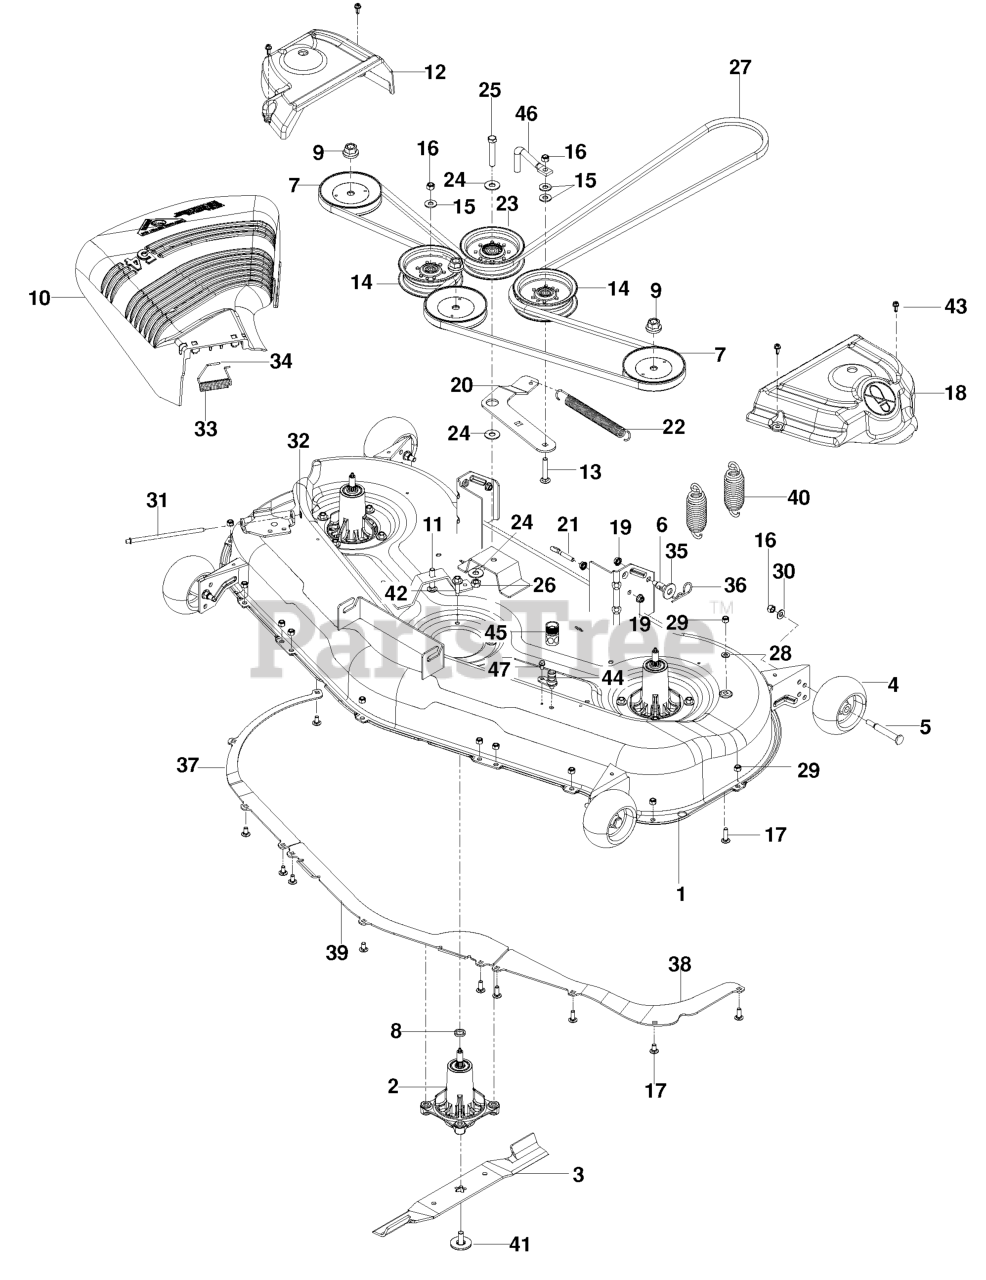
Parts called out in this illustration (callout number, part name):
1	DECK W/DECALS - RZ54
2	MANDREL GREASABLE
3	BLADE.BAGGING.54"
4	GAUGE WHEEL
5	SHOULDER BOLT 1/2X2-5/8 ZD SPE
6	STUD.FASTNER.W/ANTI-ROTATE
7	PULLEY
8	WASHER-SPACER
9	LOCKNUT - 9/16
10	DEFLECTOR, 54"
11	RHSNB 3/8C X 2
12	BELT SHIELD, RT
13	CARRIAGE BOLT 3/8-16 X
14	PULLEY.IDLER.2006
15	WASHER 3/8 FLAT
16	NUT 3/8-16 NYLOC
17	BOLT 5/16C X 3/4" CARRIAGE
18	BELT SHIELD, LT
19	5/16-18 NYLOC FLANGE NUT
20	ARM.IDLER.BLACK
21	EYE BOLT 5/16 X 3.50
22	SPRING, DECK BELT
23	PULLEY.IDLER.MWR.STATI.LH
24	WASHER 7/16 FLAT ZD
25	BOLT 7/16-14 X 2-1/2 GR 5 ZD
26	7/16-14 HEX NUT W/NYL RING ZD
27	BELT.DECK.52".54"
28	FLAT WASHER 5/16 SAE
29	NUT 5/16 NYLOC
30	WASHER 3/8 SAE FLAT
31	ROD, HINGE
32	PUSH NUT
33	TORSION SPRING
34	CAP-SLEEVE
35	WASH USS FLAT 1/2
36	HAIRPIN #4
37	BAFFLE, RIGHT 54"
38	BAFFLE LEFT 54
39	BAFFLE, CENTER, 54"
40	SPRING
41	BLADE BOLT ASSY-7/16" TB REPL
42	WASHER HEAD SCREW
43	SCREW- 1/4-20 X 5/8
44	PORT.WASHOUT
45	COUPLING.QUICK CONNECT
46	BELT KEEPER 5"
47	BOLT 1/4-20 X 1/2 HWST
